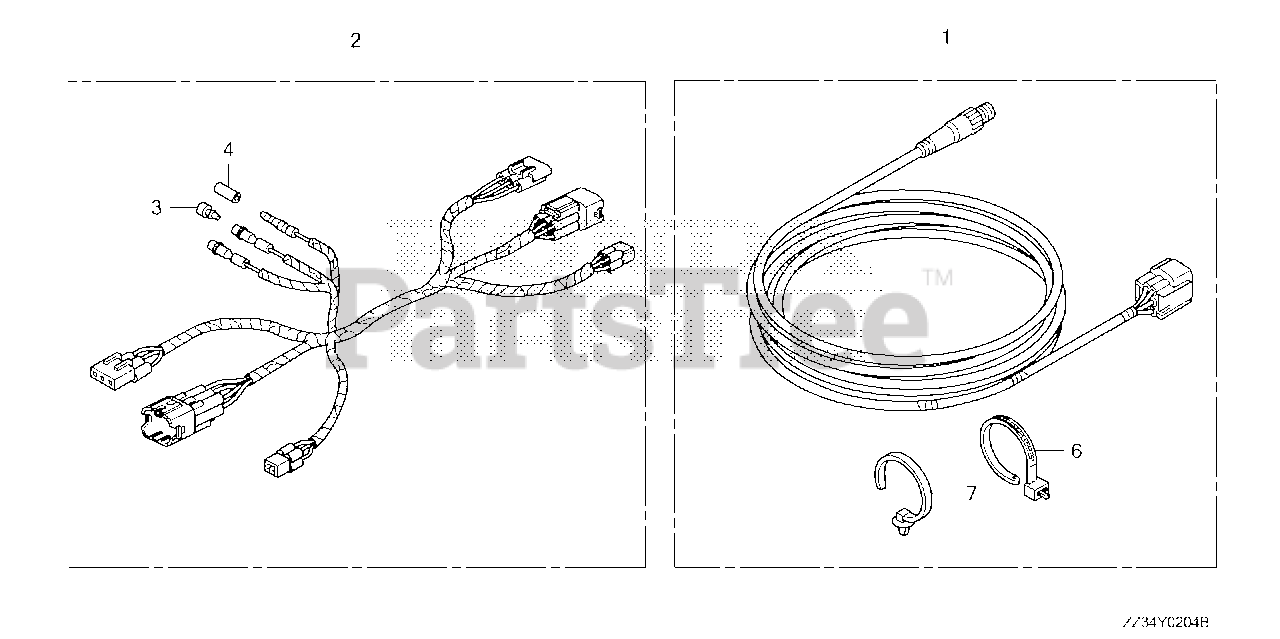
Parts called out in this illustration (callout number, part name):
1	KIT, CABLE (6FT) (NMEA) (NOT AVAILABLE)
2	HARNESS ASSY., REMOTE CONTROL SUB
3	PLUG, CONNECTOR (INNER)
4	PLUG, CONNECTOR (OUTER)
6	TIE, CABLE
7	CLIP, HARNESS BAND (155.3MM) (BLACK)
